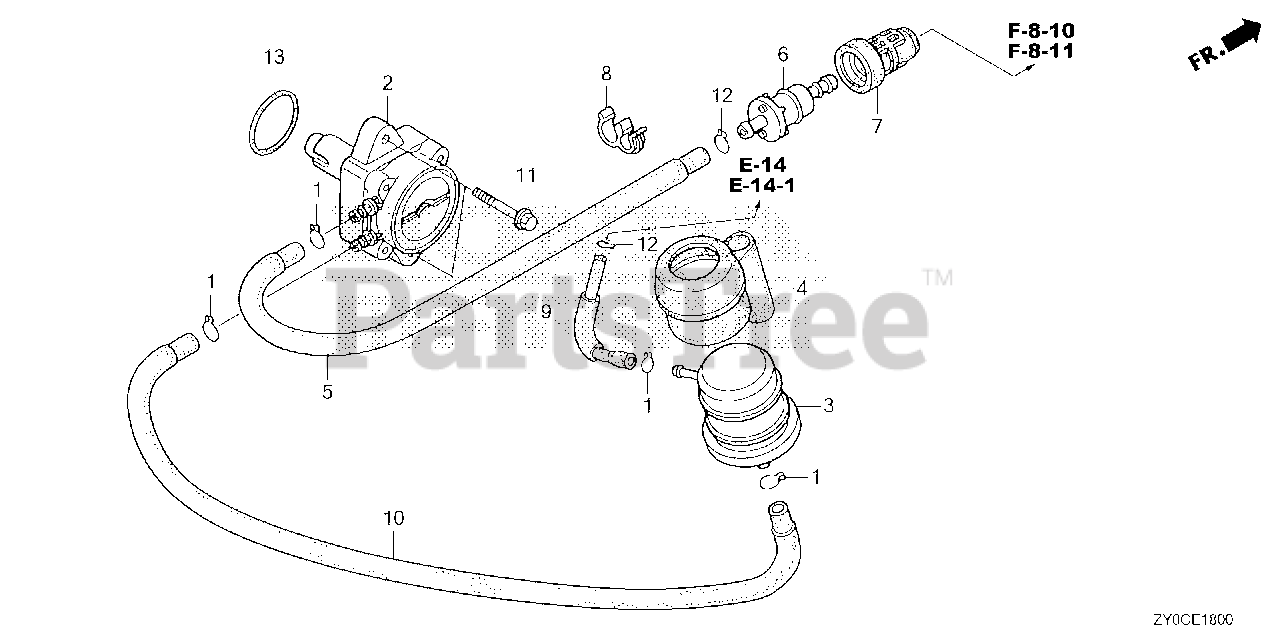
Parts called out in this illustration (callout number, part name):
1	CLIP, TUBE (ENGINE NO.)
2	PUMP ASSY., FUEL (MSDS)
3	CHAMBER, FUEL
4	SUSPENSION, FUEL CHAMBER
5	TUBE B, FUEL
6	FILTER, FUEL
7	SUSPENSION, STRAINER
8	CLAMP, TUBE (7.5-11.5) (BLACK)
9	TUBE D, FUEL
10	TUBE C, FUEL
11	BOLT, FLANGE (6X22)
12	CLIP, TUBE (B10)
13	O-RING (31.2X2.4)
